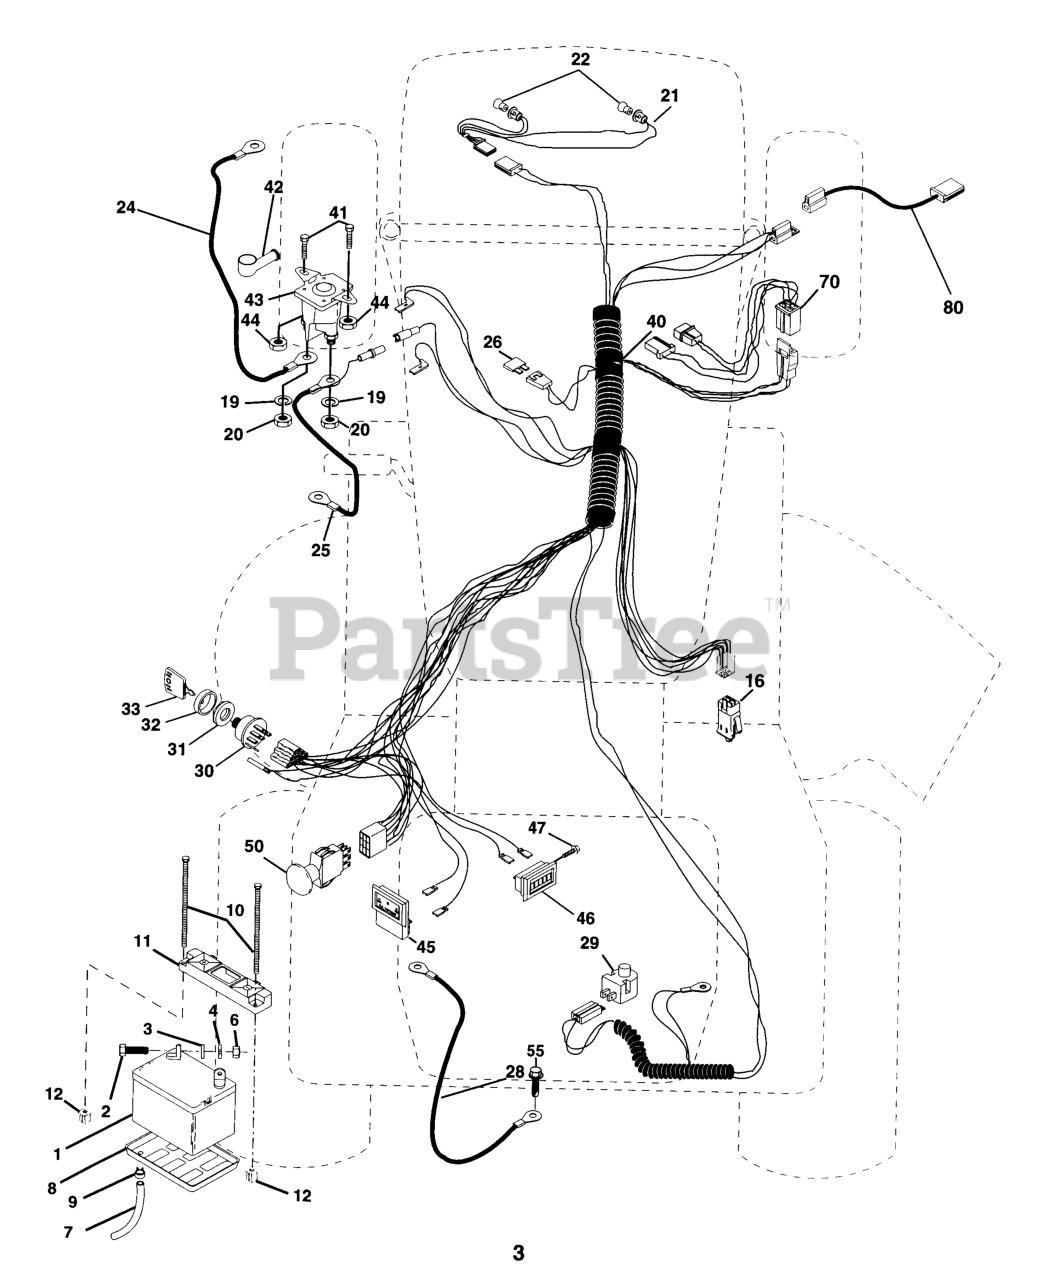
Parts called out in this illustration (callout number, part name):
1	BATTERY 12 VOLT 30 AMP WET
2	BOLT.HEX.1/4.X.3/4.DICHROMATE
3	WASHER
4	LOCKWASHER
6	NUT
7	PLASTIC TUBE
8	BATTERY TRAY T
9	HOSE CLAMP T
10	BOLT 1/4-20 X 7.5
11	BATTERY HOLDDOWN FRONT MOUNT
12	NUT, PUSH NYLON 1/4" BATTERY
16	SWITCH INTERLOCK
19	LOCKWASHER
20	NUT
21	HARNESS LIGHT SOCKET
24	BATTERY CABLE GT
25	CABLE BATTERY 6 GA 22" W/16W
28	CABLE GROUND 6 GA 21" 90T BLK
29	RP.SWITCH.PLUNGER.NC.GRAY
30	SWITCH.IGNITION.4.POSITION
31	NUT IGNITION
32	COVER SWITCH KEY
33	KEY.MOLDED.GENERIC
40	IGN HARNESS
41	BOLT
42	TERMINAL COVER
43	SOLINOID
44	Nut Keps Hex 1/4-20 Unc
45	AMMETER
46	HOUR METER T
47	Screw 10-24 x 1/2 Black
50	SWITCH PTO 3 PDT
55	Screw THDROL 5/16-18 x 1/2 TYT
70	HARNESS ENGINE
80	HARNESS, CLUTCH
